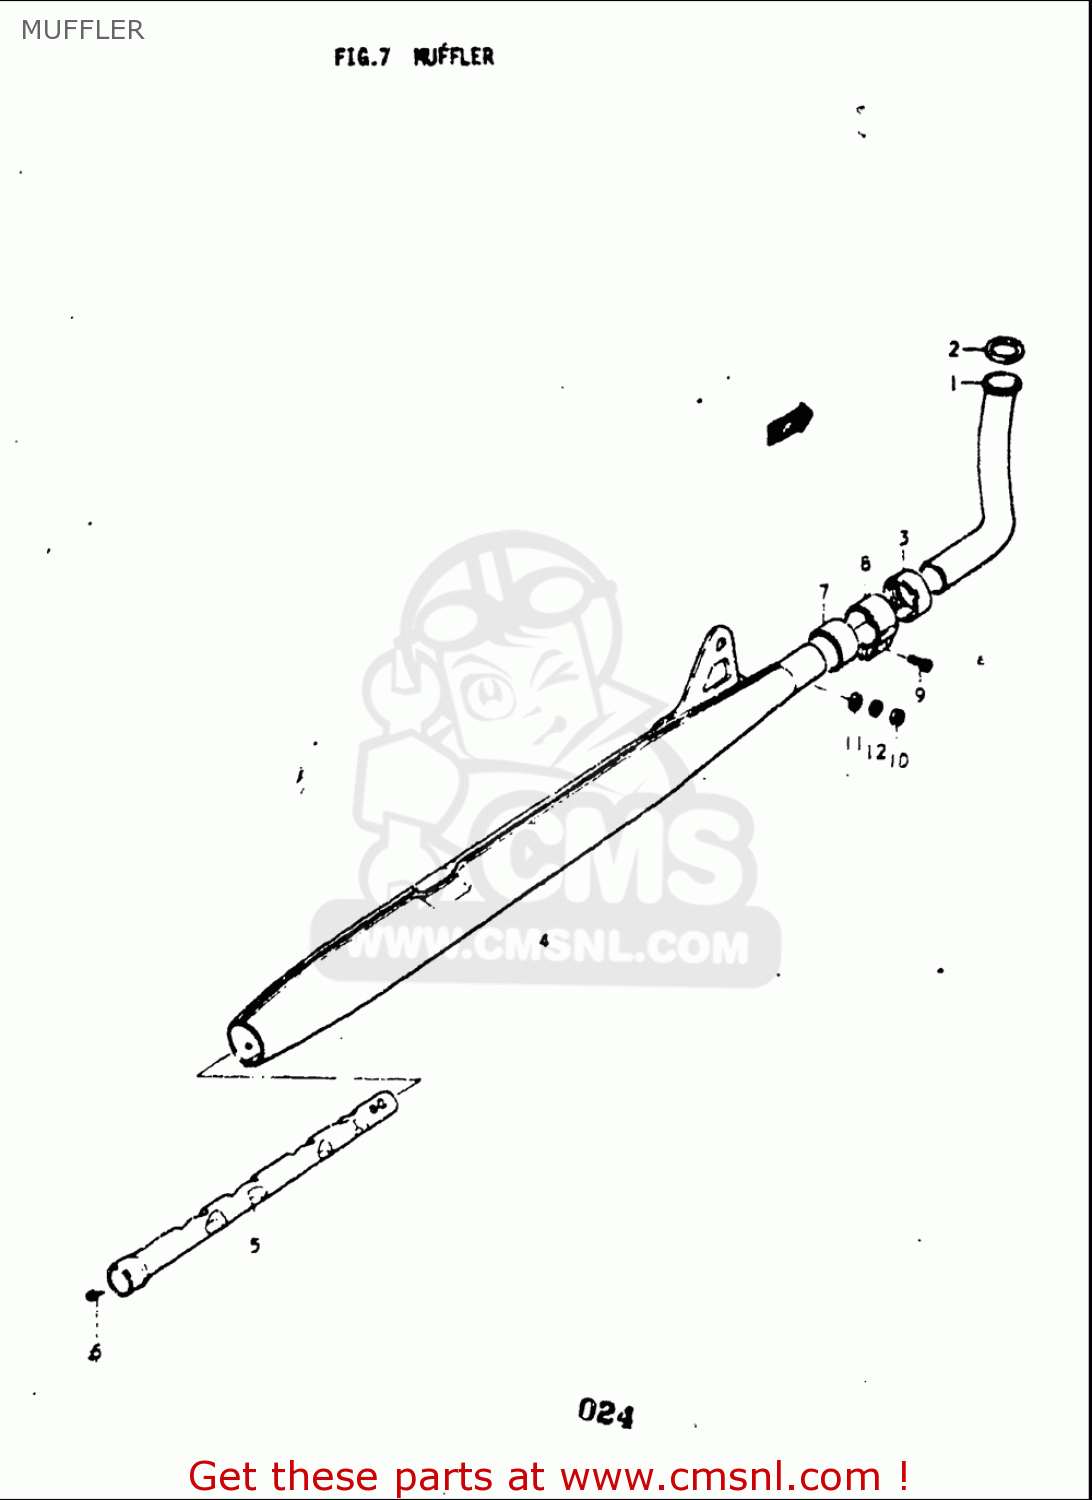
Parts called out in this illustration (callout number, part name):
1	PIPE,EXHAUST
2	GASKET,EXHAUST PIPE (NAS)
3	CLAMP,EXHAUST PIPE
4	MUFFLER ASSY
5	PIPE,BAFFLE
6	SCREW(5X6)
7	CONNECTOR,MUFFLER
8	CLAMP
9	SCREW
10	NUT
11	WASHER
12	WASHER,LOCK
